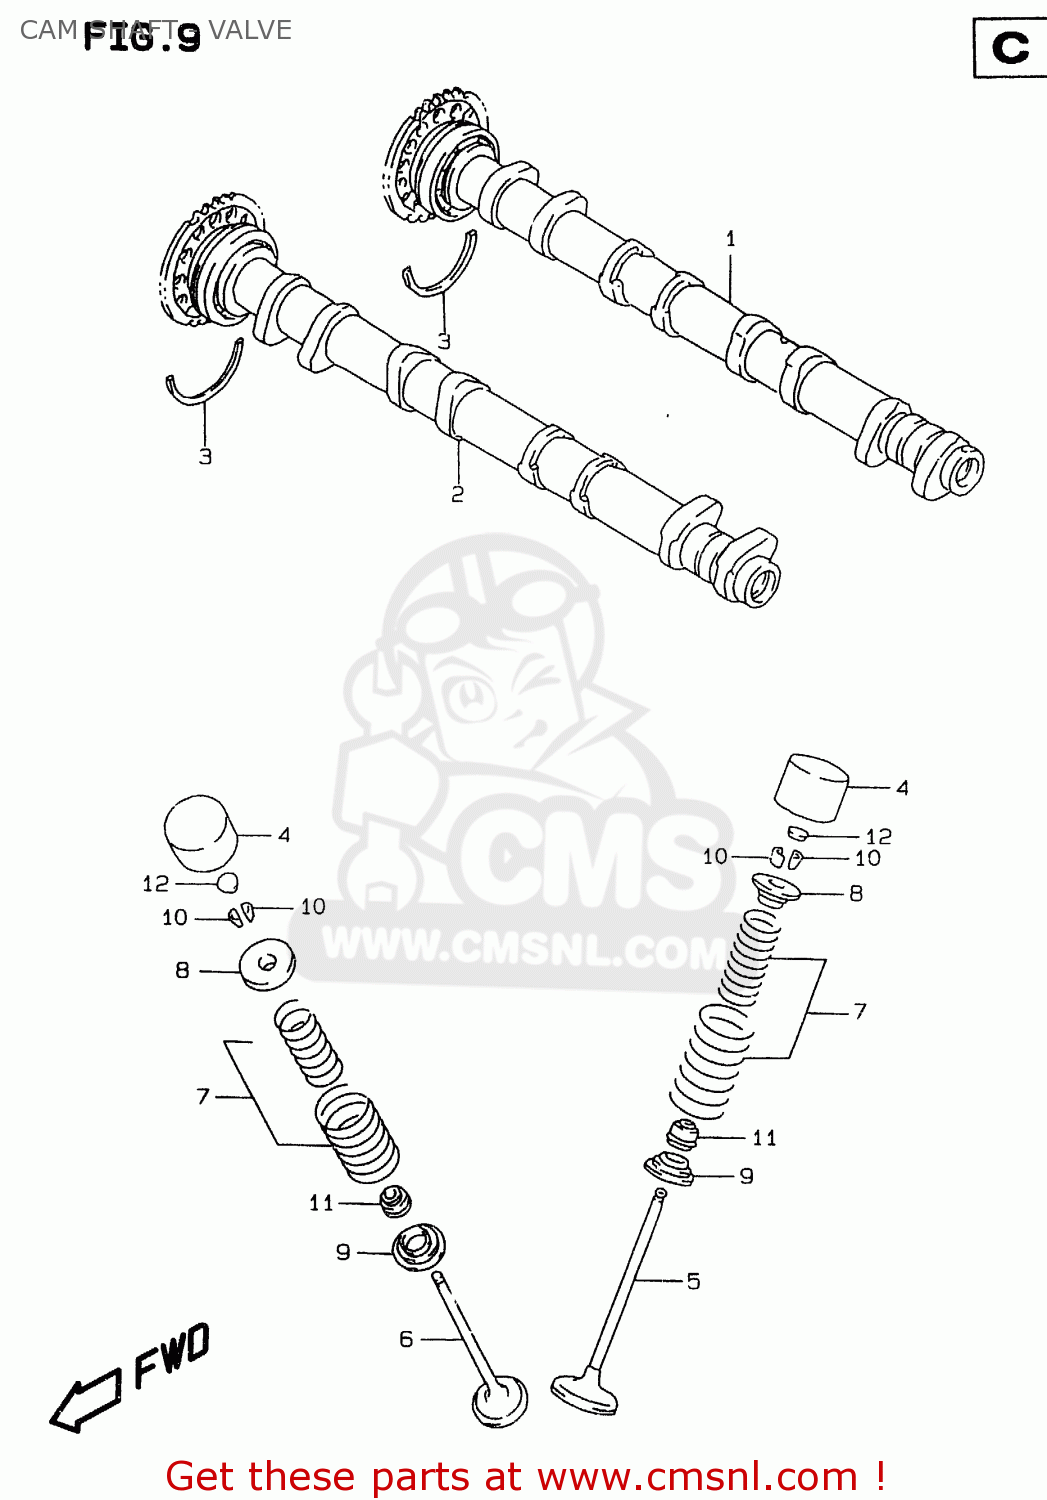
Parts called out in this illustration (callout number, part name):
1	CAMSHAFT,INTAKE
2	CAMSHAFT COMP,EXHAUST
3	C RING
4	TAPPET
5	VALVE,INTAKE
6	VALVE,EXHAUST
7	SPRING SET,VALVE
8	RETAINER,VALVE SPRING
9	SEAT,VALVE SPRING
10	COTTER VALVE
11	SEAL,OIL(4.5X10X8)
12	SHIM,TAPPET
